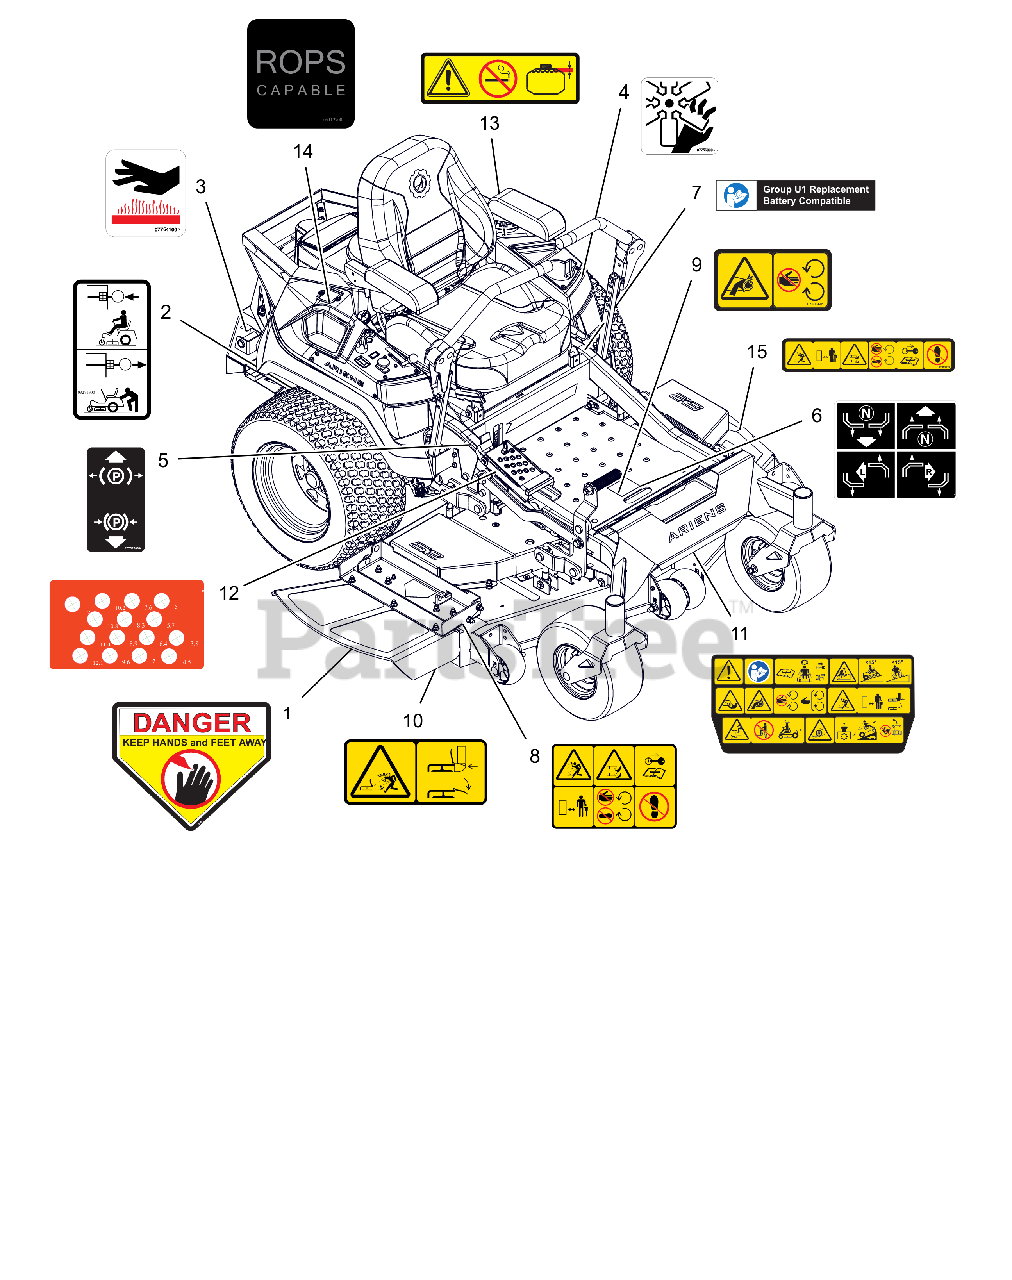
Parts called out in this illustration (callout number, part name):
1	DECAL, DANGER
2	DECAL, TRANSMISSION DISCONNECT
3	DECAL, HOT SURFACE
4	DECAL, DANGER FAN
5	DECAL, PARKING BRAKE LEVER
6	DECAL, INSTRUCTIONAL-STEERING
7	DECAL, U1 BATTERY REPLACEMENT
8	DECAL, SAFETY - MOWER DECK
9	DECAL, SAFETY - GUARDING
10	DECAL, SAFETY - DECK GUARDING
11	DECAL, MAIN SAFETY
12	DECAL, APEX HOC METRIC
13	DECAL, FUEL WARNING
14	DECAL, ROPS LOCATION
15	DECAL, DECK SAFETY
